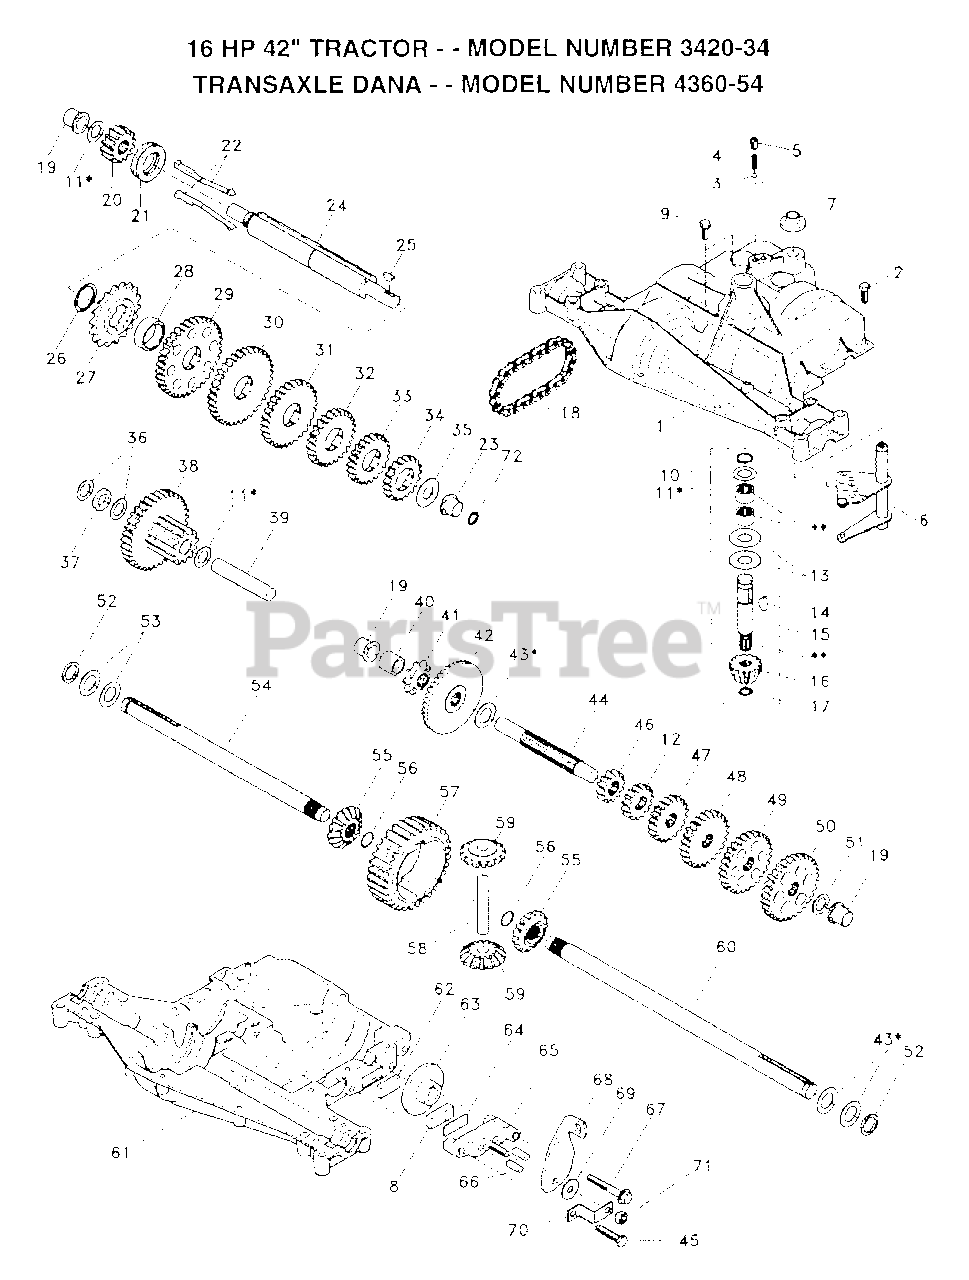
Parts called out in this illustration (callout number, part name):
4	"SPRING, DETENT LT"
5	"SCREW, SET LT"
6	SHIFTER.ASM.KIT.
7	SHIFTER BOOT
8	PUCK T
9	SCREW TAP W/SEAL
10	RETAINING RING LT
11	ASM KIT SHIM 4689
13	WASHER T
14	WOODRUFF KEY
17	"RING,RETAINING LT"
18	"CHAIN,24 PTCH LT"
19	BEARING.FLNG.5510
20	GEAR SPUR 14T
21	COLLAR CLUTCH
22	KIT.ASM.CLUTCH KY
23	"FLANGE, BEARING"
24	SHAFT INTERM
25	WOODRUFF KEY
26	"RING,RETAINING LT"
27	SPROCKET 18T T
28	SPACER YT
29	KIT.GEAR.12/37TH
31	GEAR SPUR 30T
32	GEAR 25T LT
33	GEAR SPUR 22 TT
34	SPUR GEAR 19T
35	"WASHER, PLAIN LT"
36	WASHER 025
37	SPACER
38	ASSM GEAR COMB
39	SHAFT IDLER
40	SPACER T
41	SPROCKET 9T LT
43	ASM KIT SHIM
44	SHAFT T
45	"SCREW, TAPPING LT"
48	"GEAR, SPUR 25T LT"
49	GEAR 28T T
50	"GEAR, SPUR 31T LT"
51	WASHER 060
52	NEOPRENE WASHER
53	WASHER 031
55	GEAR LT
56	"RING,RETAINING LT"
58	SHAFT T
59	"GEAR,MITER 15T YT"
62	PUCK T
63	BRAKE DISC. T
64	SPACER LT
66	PIN T
69	WASHER LT
71	NUT.LOCK.5/16-24
72	SQUARE RING
